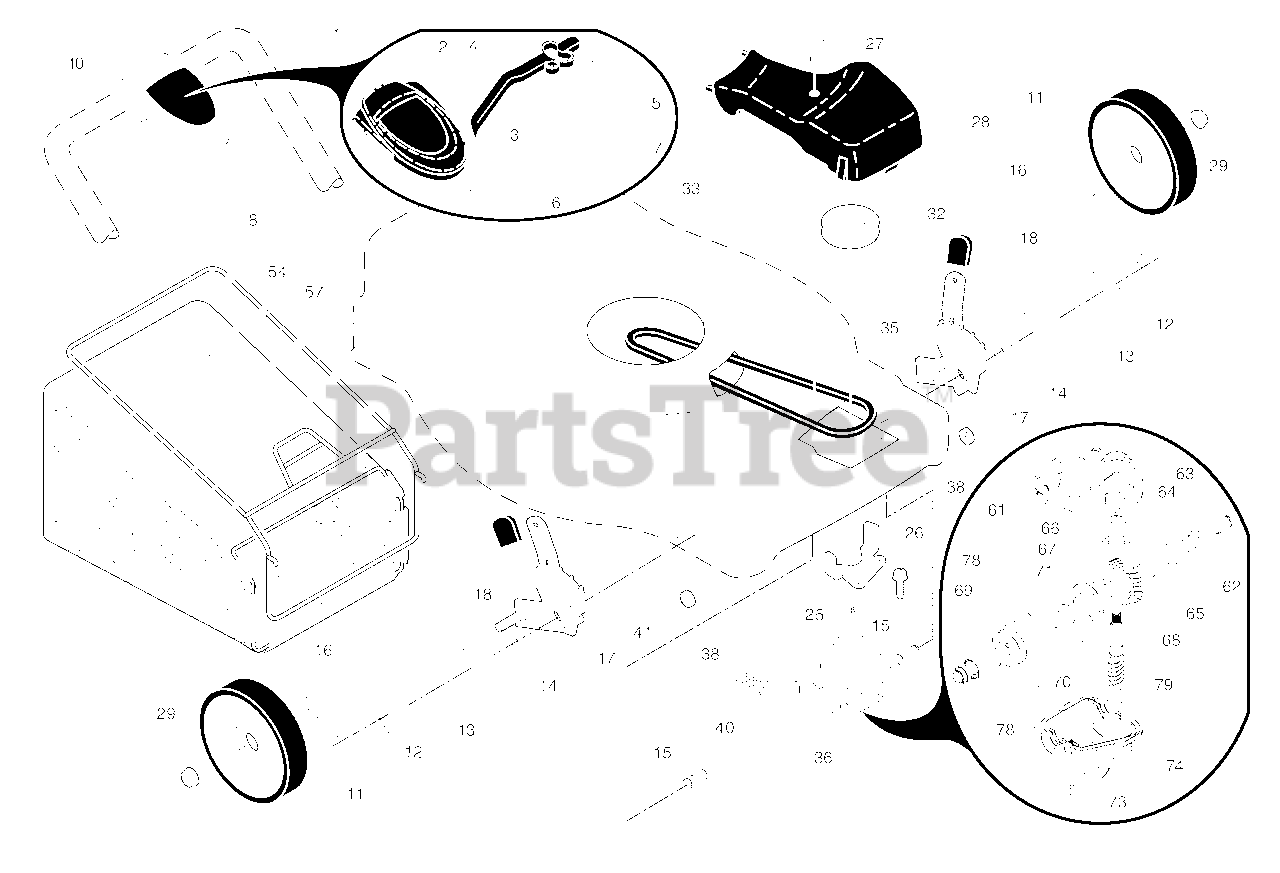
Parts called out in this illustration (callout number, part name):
1	Drive Control Assembly
2	Cover, Drive Control, Top
3	Pulley
4	Lever, Drive Control
5	Cover, Drive Control, Bottom
6	Screw, Torx Head #8 x 5/8
7	Mounting Bracket, Drive Control
8	Cable, Drive Control
10	Decal, Drive Control
11	Wheel & Tire Assembly
13	Gear, Pinion
14	Dust Cover
15	Drive Pawl
16	Washer, Flat 3/8
17	Bearing, Wheel Adjuster
18	Selector Knob
25	Belt Keeper
26	Screw, Hi-Lo Thread #12 x 5/8
27	Pan Head Tapping Screw #10-24 x 2-3/4
28	Drive Cover
29	Locknut, Hex
32	Drive Pulley
35	Kit, Wheel Adjuster, LH
36	Gear Case Assembly, Complete
38	Locknut, Hex 1/4-20
41	Kit, Wheel Adjuster, RH
54	Grassbag Assembly
57	Frame, Grassbag
61	Case, Upper
62	Shaft, Output
63	Seal, Output Shaft
66	Seal, Worm Shaft
67	Bearing, Ball
68	Gear, 28 Teeth
69	Fixed Dog Clutch
70	Pin
71	Movable Dog Clutch
73	Screw, Case
74	Case, Lower
78	Spring, Leaf
79	Shaft, Worm
